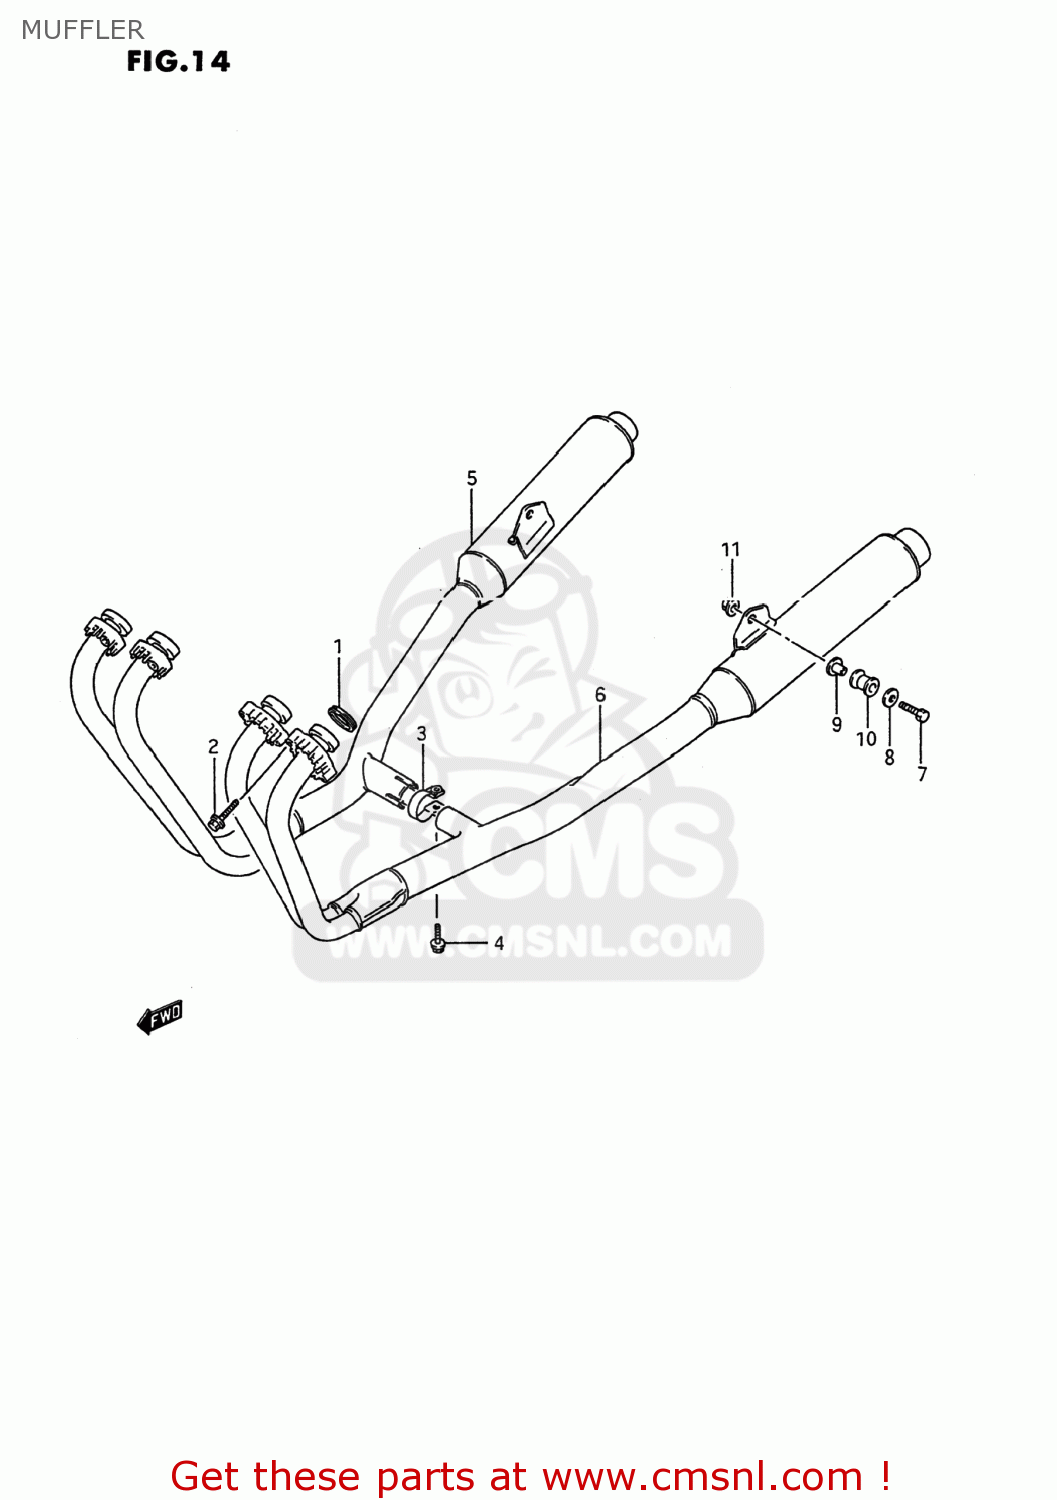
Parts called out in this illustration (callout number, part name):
1	GASKET,EXHAUST (NAS)
2	BOLT
3	CLAMP,MUFFLER CONNECTOR
4	BOLT
5	MUFFLER R.
6	MUFFLER ASSEMBLY,LEFT
7	BOLT
8	WASHER (8.5X20X1.6)
9	SPACER(8.6X12X24.2)
10	CUSHION
11	NUT
